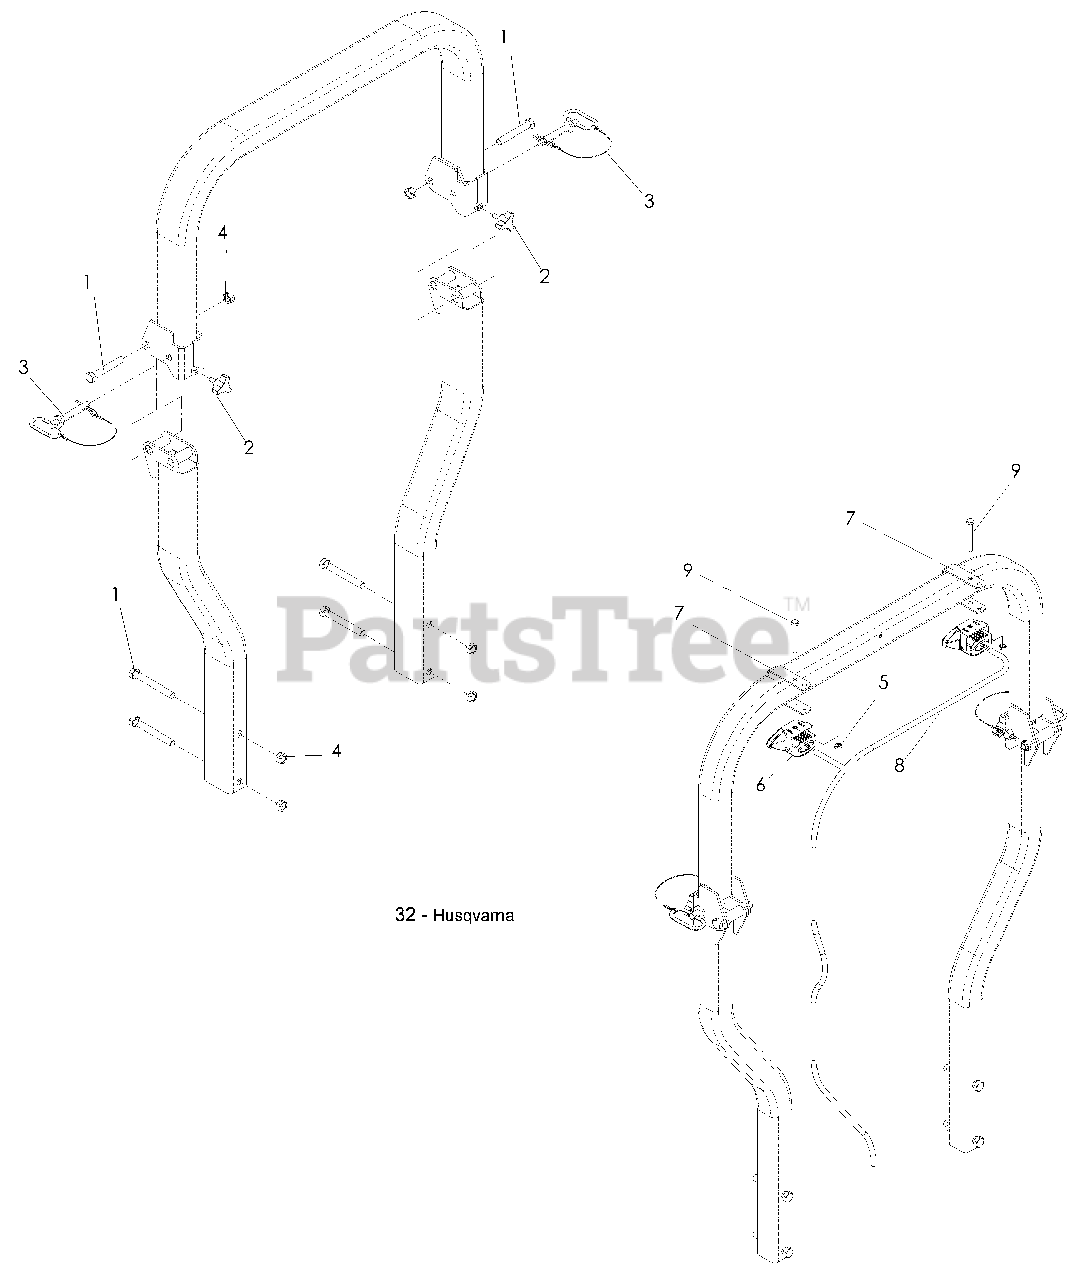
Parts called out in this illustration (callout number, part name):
1	HCS ½-13 x 3¼
2	KNOB w/STUD
3	LANYARD W/PIN ½"
4	NUT ½-13, CTRLK
5	NUT 5/16-18, JAM
6	LIGHT w/BRKT & HRDWARE
7	MOUNTING BRKT, LIGHT
8	LIGHT HARNESS
9	HCS 5/16-18 x 2½
